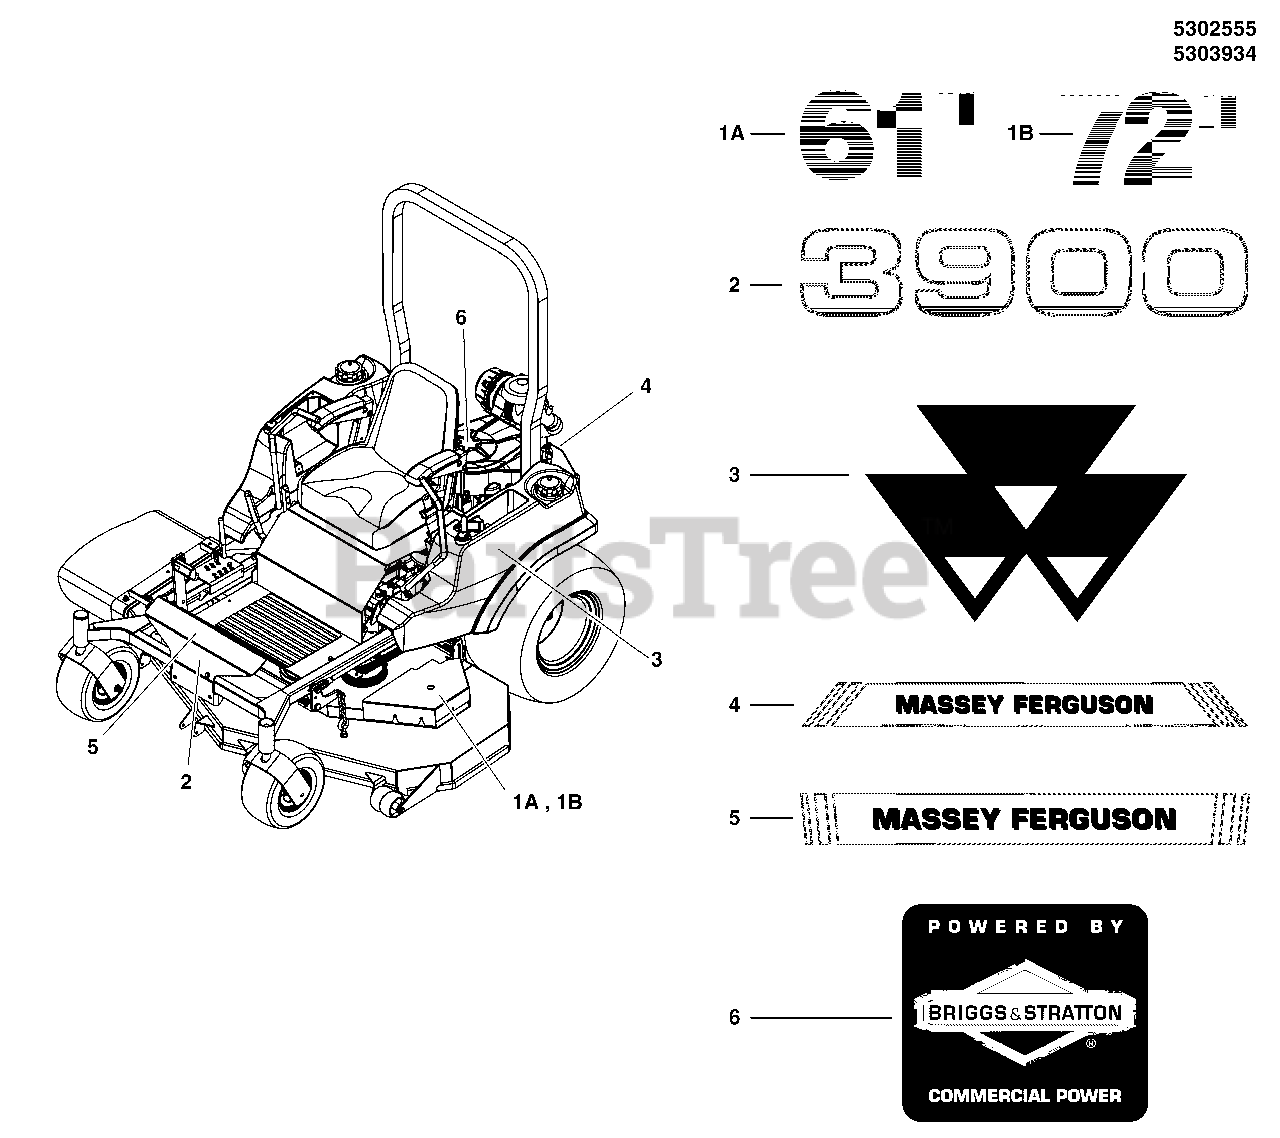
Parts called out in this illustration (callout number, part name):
1A	DECAL, 61
1B	DECAL, 72
2	DECAL, MF MODEL, 3900
3	DECAL, LOGO, SIDE PANEL
4	DECAL, MASSEY LOGO, BACK
5	DECAL, MASSEY LOGO, FRONT
